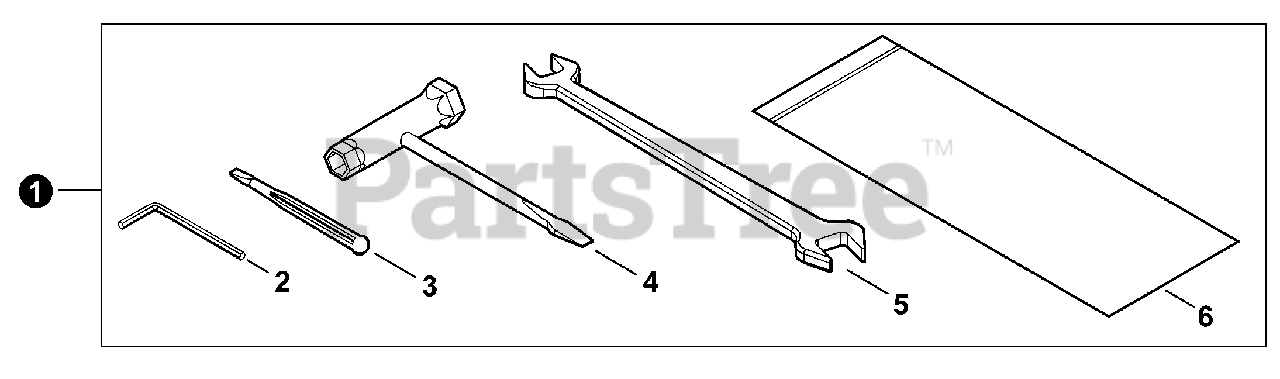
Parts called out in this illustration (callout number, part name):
1	TOOL KIT, SERVICE
2	WRENCH, ALLEN 4 MM
3	SCREWDRIVER, PLASTIC
4	T-WRENCH 13×19 MM
5	SPANNER 8×10
6	BAG, TOOL
